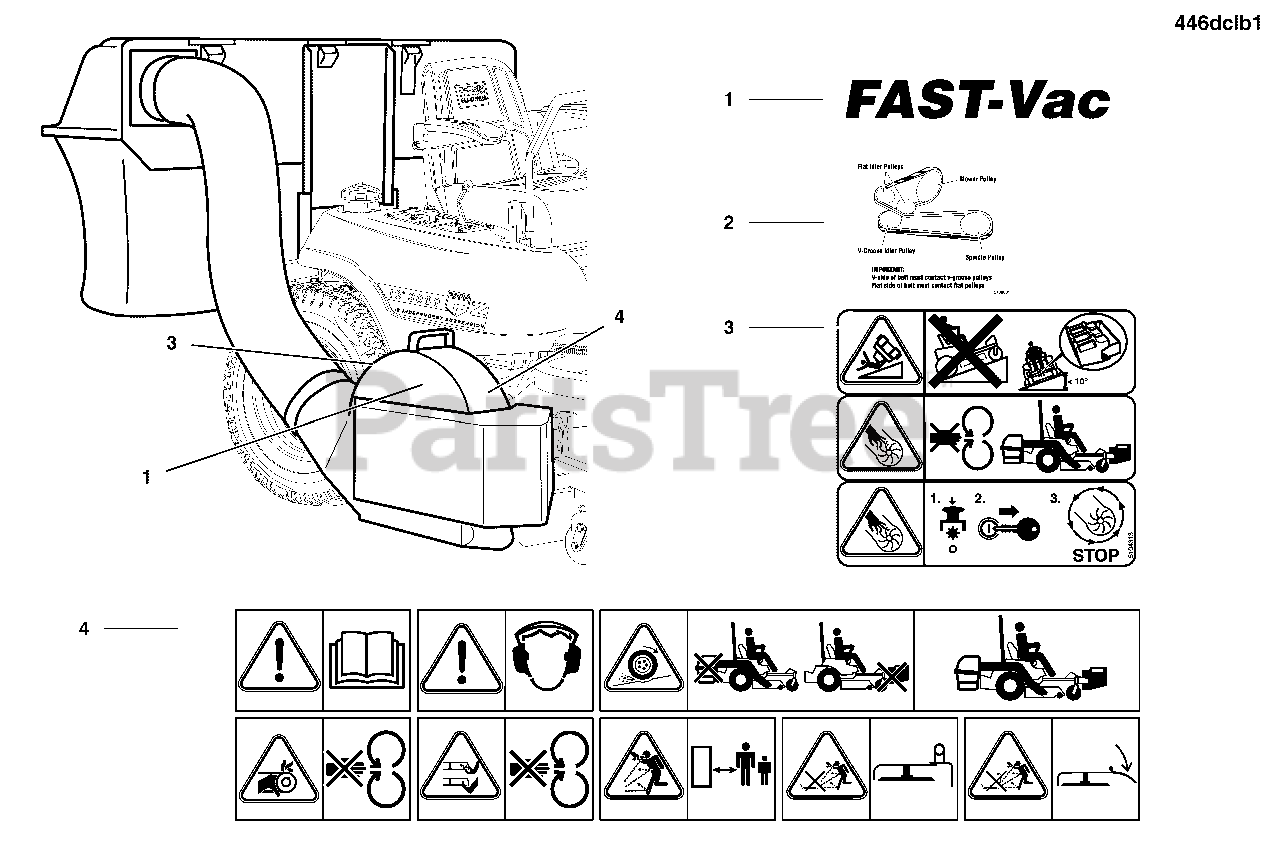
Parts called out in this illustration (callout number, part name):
1	DECAL, Fast-Vac
2	DECAL, Belt Routing
3	DECAL, BLOWER, SMALL, ICONS
4	DECAL, BLOWER, MAIN, LARGE, ICONS
